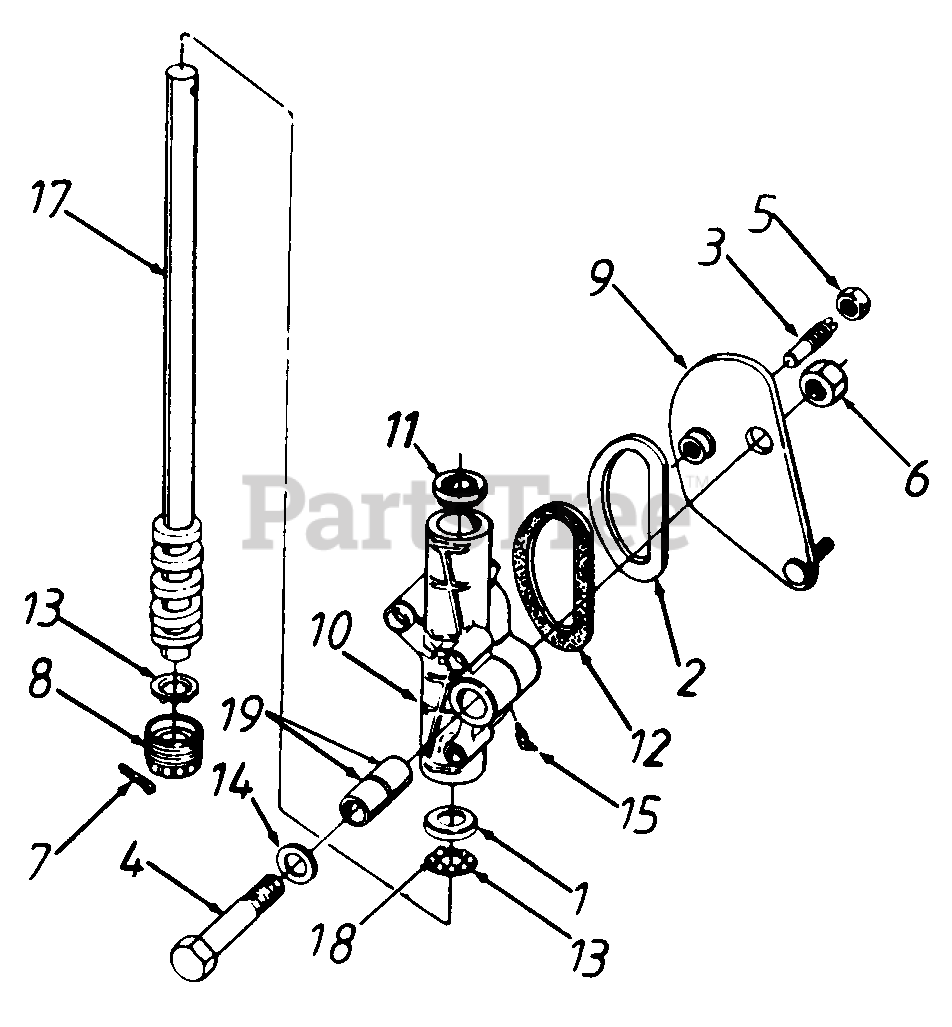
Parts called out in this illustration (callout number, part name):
1	Bearing Cup
2	Seal Retainer
3	Cam Follower
5	Hex Jam Nut 9/16-18 Thd.
6	Hex Crown L-Nut 5/8-18 Thd.
7	Cotter Pin 1/8" Dia.
8	Adjustment Plug Ass'y.
9	Steering Arm Ass'y.
10	Steenng Gear Hsg.
12	Seal
13	Ball Retainer
14	Fl-Wash. .781" I.D. x 1.25" O.D.
15	Grease Fitting
17	Steering Shaft Ass'y.
18	Ball Bearing
19	Housing Bushing
